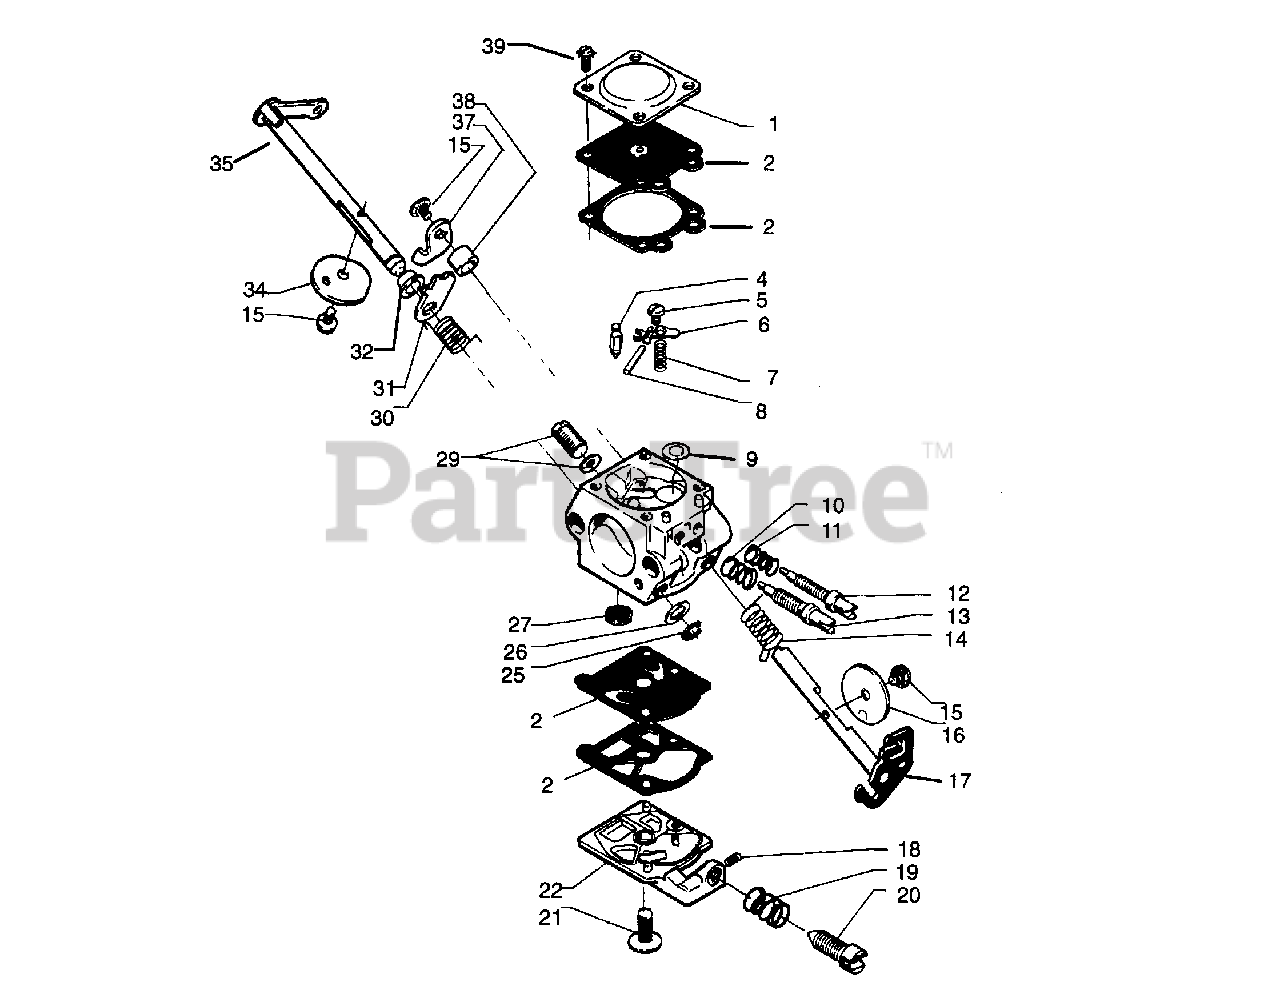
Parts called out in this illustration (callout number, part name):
2	Gasket Kit
6	Metering Lever
9	Ring
11	Spring
12	Low Speed Screw
13	High Speed Screw
17	Shaft Ass'y.
20	Adjusting Screw
24	Diaphragm
29	Valve Ass'y.
30	Spring
35	Shaft Ass'y.
39	Screw
